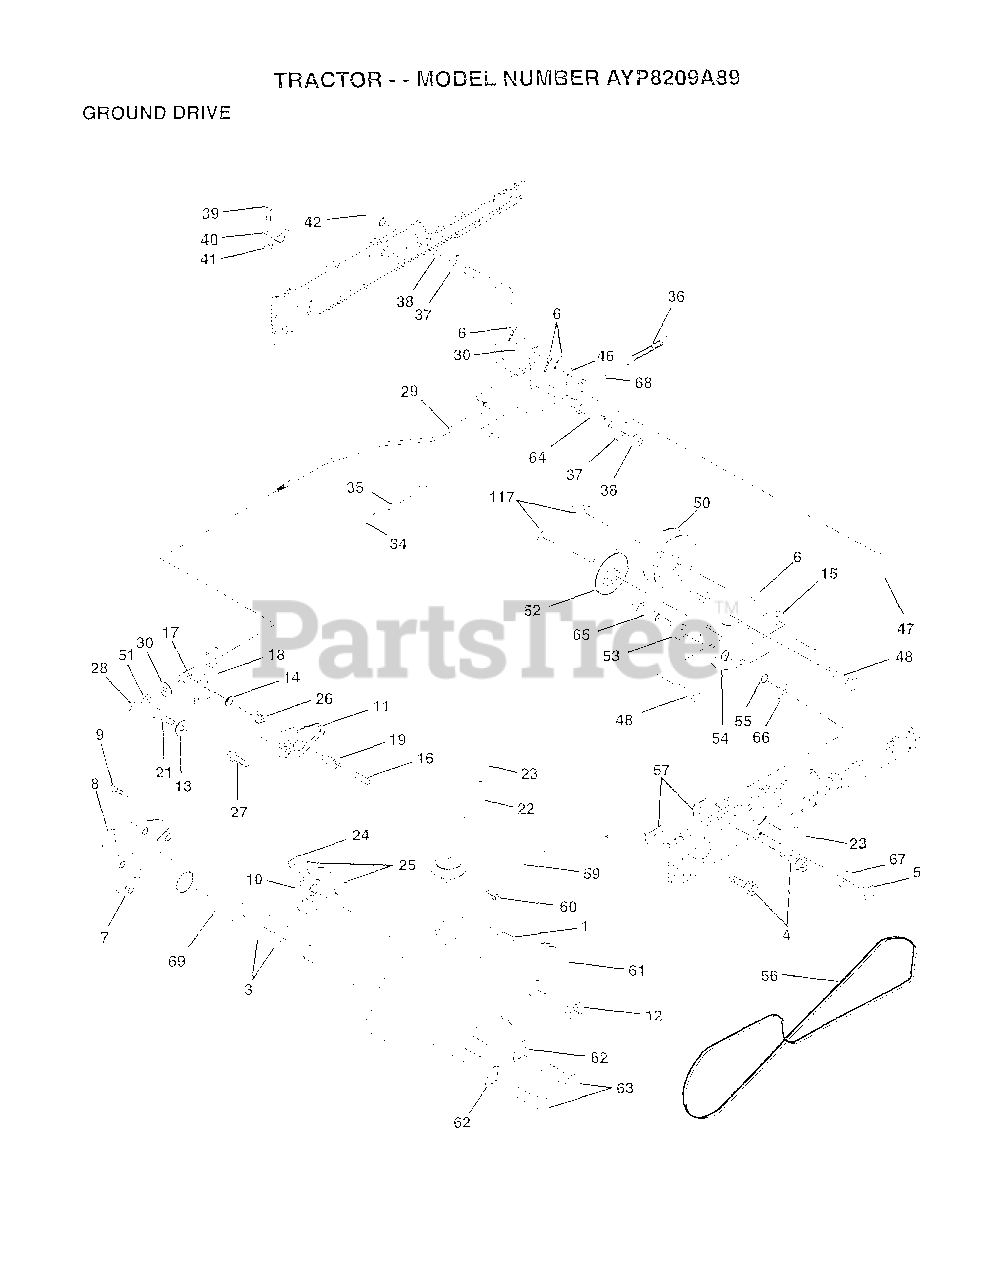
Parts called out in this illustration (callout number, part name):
3	WASHER T
6	COTTER PIN
8	KLIP RING
9	BOLT.HUB.WHL.REAR
10	BRAKE.DISC.
11	YOKE BRAKE DISC
12	"LOCKNUT,1/2-20UNF"
13	WASHER SPECIAL
14	BUSHING LEVER BKT
15	WASHER
16	SCREW SET 1/4-20
17	"SPRING,ROD BRAKE"
18	LEVER BRAKE GT
19	CAM BRAKE DISC GT
21	SCREW FLT 1/4X28
22	GEAR SHFT LVR T
23	KNOB
24	SUPPORT PUCK BRKE
25	PUCK BRAKE TOP
26	SPRING RET BRAKE
27	SCREW HX WASH
28	NUT
30	WASHER HYT
35	ROD BRAKE PART GT
36	SPRING.GRND.DRIVE
37	WASHER
38	BUSHING.NYLINER
39	SCREW
40	ACT-SWITCH T
42	PEDAL COVER T
46	RETAINER.SPRING
47	ROD.CLUTCH
48	BOLT.3/8-16X1.50
50	FLAT IDLER PULLEY
52	PULLEY.IDLER.V.GR
53	WASHER T
54	CLUTCH.ARM.ASM
55	"LY, BEARING"
56	BELTV.GR.DR.83.
57	BRACKET.ROD.SHIFT
59	ROD SHIFT HI LO
60	CONNECTING LINK
62	LOCKWASHER
63	BOLT
64	SHAFT-BRAKE/CLUTC
65	AXLE BOLT
66	WASHER.HARD.BLADE
67	WASHER
68	ROLL PIN STD
69	"COVER, HUB"
